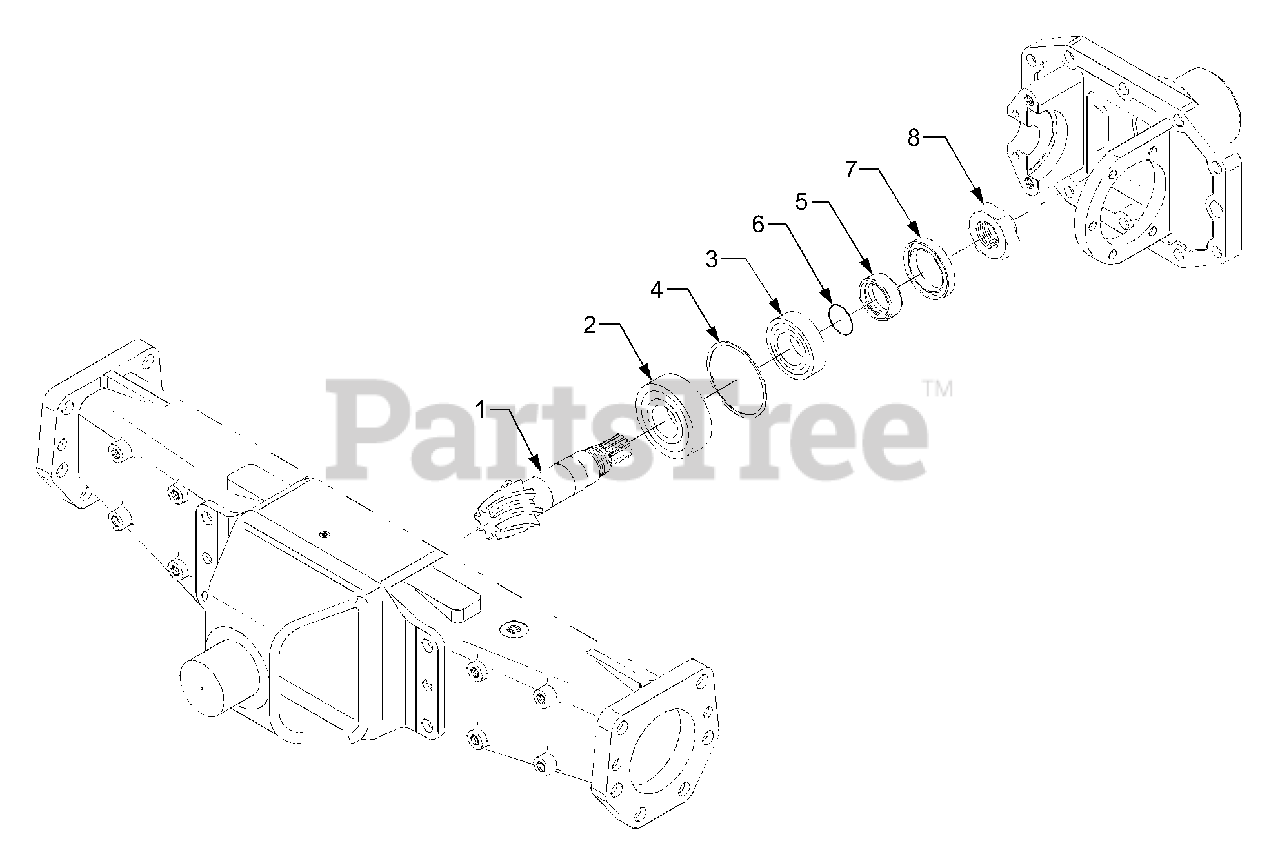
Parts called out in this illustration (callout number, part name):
1	Shaft, 8 Bevel Pinion
2	Bearing, Tapper Roller
3	Bearing, Tapper Roller
5	Collar, Oil Seal
